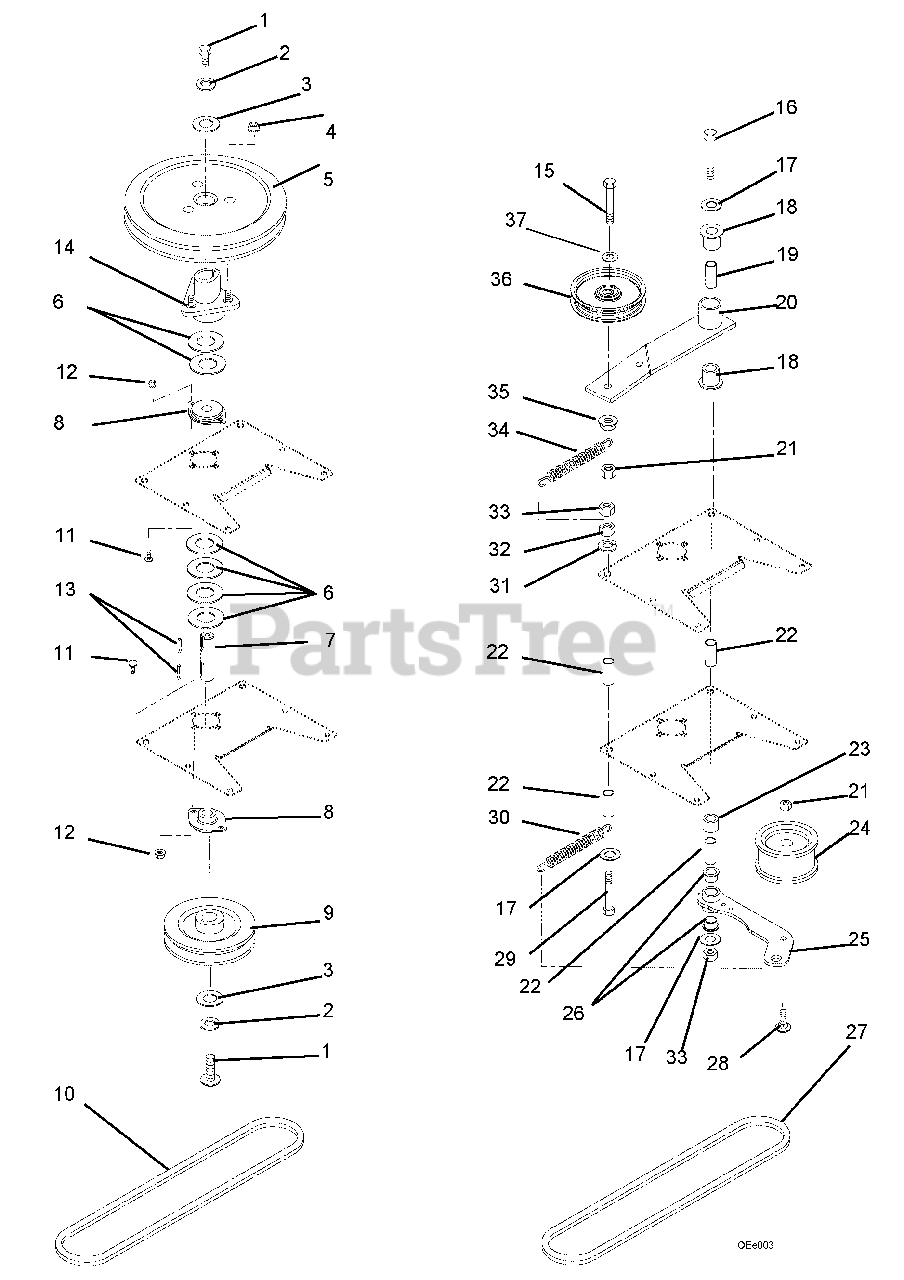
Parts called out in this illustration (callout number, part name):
1	Bolt, Hex .25-20 x .75 Grade 5
2	Washer-Locking .25 x .062 Regular
3	Washer-Flat-Steel .344 x 1.125 x .135
4	Nut-Spin Lock-Flange .312-18
5	Pulley-V 9.0 x 1.25
6	Washer-Flat-Steel .755 x 1.25 x .125
7	Shaft, Zoom Snow Throw
8	Bearing, 2 Bolt Flange-.75 ID
9	Sheave, Blower- 4.25 Diameter
10	Belt, HA Raw Laminated (Engine clutch to snow thrower drive pulley.)
11	Bolt-Round Head Square Neck .31-18 x .75 Grade 5
12	Nut-Locking-Top-Flange .31-18
13	Key-Square .187 x .50 x .187 Hardened
14	Hub Assembly
15	Bolt-Hex .38-16 x 2.25 Grade 5
16	Bolt, Hex .50-13 x 7.00
17	Washer-Flat-Steel .531 x 1.06 x .095
18	Bushing, Nylon, Flange .762 x 1.0 x .580 x 1.48
19	Bushing, Steel .560 x .745 x 2.04 Steel
20	Weldment, Idler
21	Nut-Locking-Jam-Center .375-16
22	Bushing-Sleeve .500 x .750 x 1.560
23	Bushing, .516 x 1.0 x 1.05
24	Idler Flanged 3.50
25	Weldment, Idler
26	Bushing, Flanged 0.75 x 0.875 x .625 x 1.125
27	V-Belt, HA Raw Laminated (Auger drive belt.)
28	Bolt-Round Head Square Neck .38-16 x 1.75 Grade 5
29	Bolt-Hex .50-13 x 5.00 Grade 5
30	Spring, Extension
31	Washer-Locking .50 x .125
32	Nut-Hex .50-13
33	Nut-Locking-Center-Jam .500-13
34	Spring, Extension
35	Nut-Locking-Jam-Center .375-16
36	Pulley, Idler 4.00
37	Washer, Flat Steel .406 x .812 x .065
